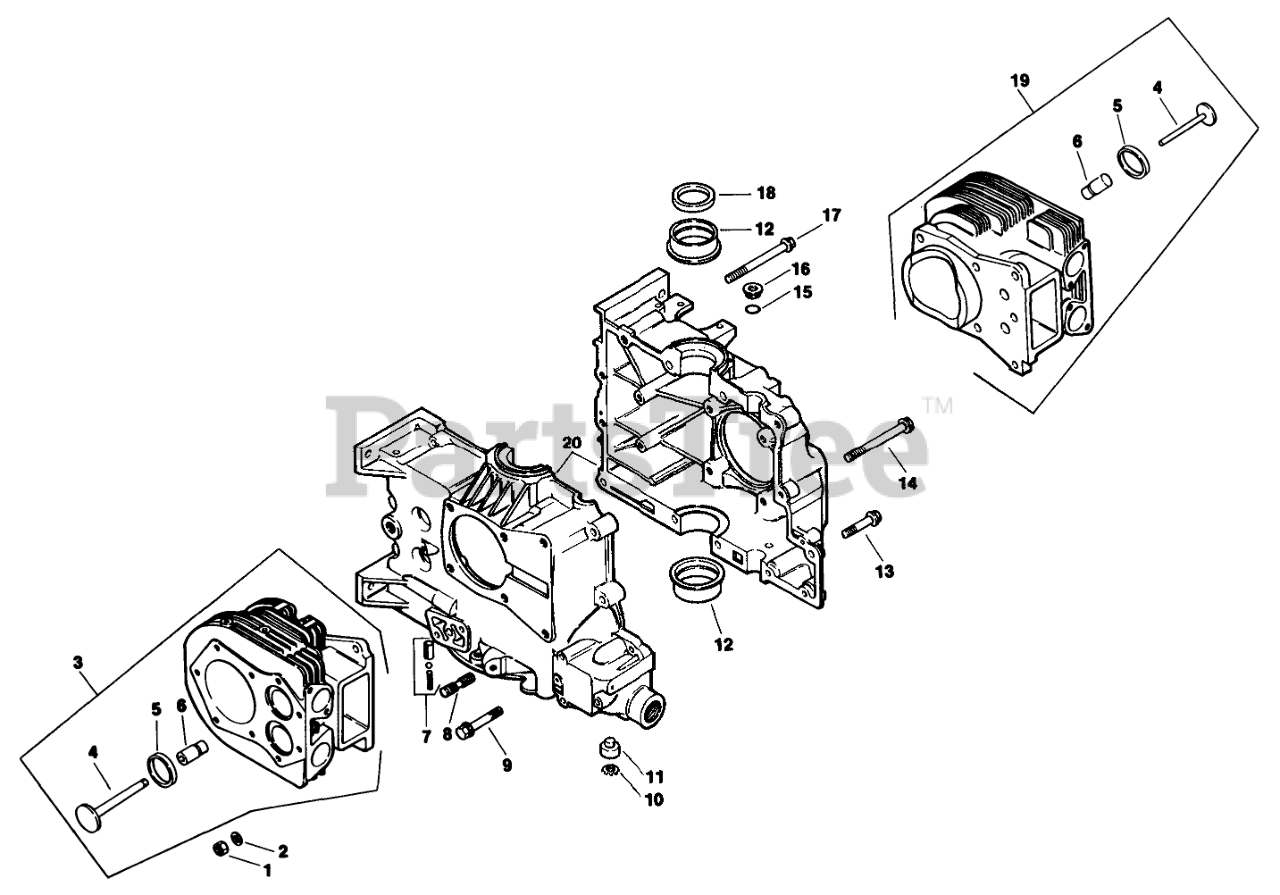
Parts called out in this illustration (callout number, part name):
2	Washer-Flat
3	Kit-#2 Cylinder Barrel (Incl. Ref. #4-6)
4	Valve-Exhaust
5	Inset-Valve Seat
6	Guide-Valve
7	Kit-Oil Relief
9	Screw-Hex Flange
10	Ring-Retaining
11	Shaft-Governor
12	Bearing-Sleeve
13	Screw-Hex Flange
14	Screw-Hex Flange
17	Screw-Hex Flange
18	Seal-ReAR Oil
19	Kit-#2 Cylinder Barrel (Incl. Ref. #4-6)
